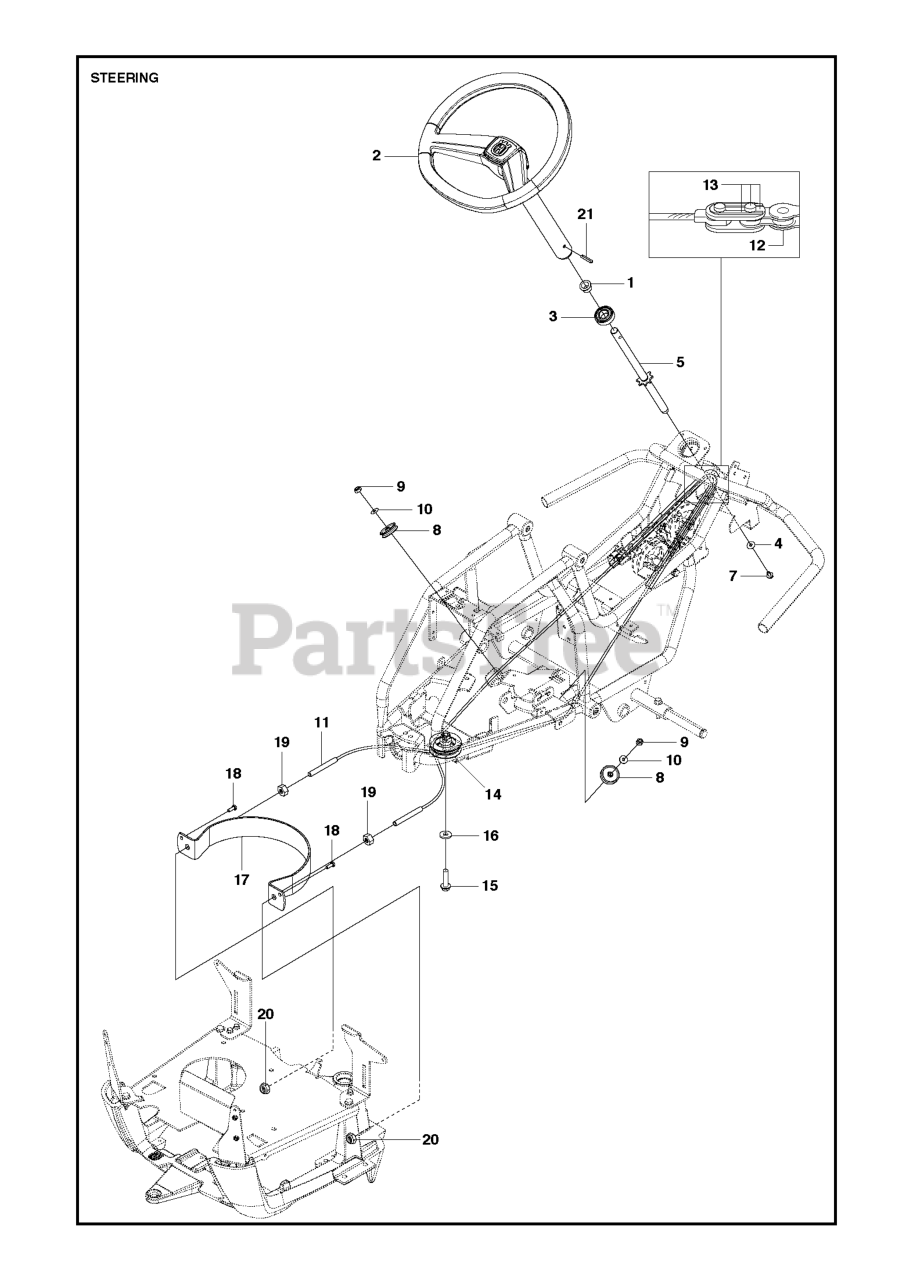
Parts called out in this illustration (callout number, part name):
2	STEERING SYSTEM
3	BALL BEARING 6004-2RS1
4	WASHER - 26X6.5X1.6
5	STEERING ROD
7	SCREW EHHFM
9	LOCKNUT M8
10	WASHER BRB 8.4X17
11	WIRE ASSY
12	STEERING CHAIN
17	GUIDE RAIL
18	SCREW
19	NUT
20	NUT
